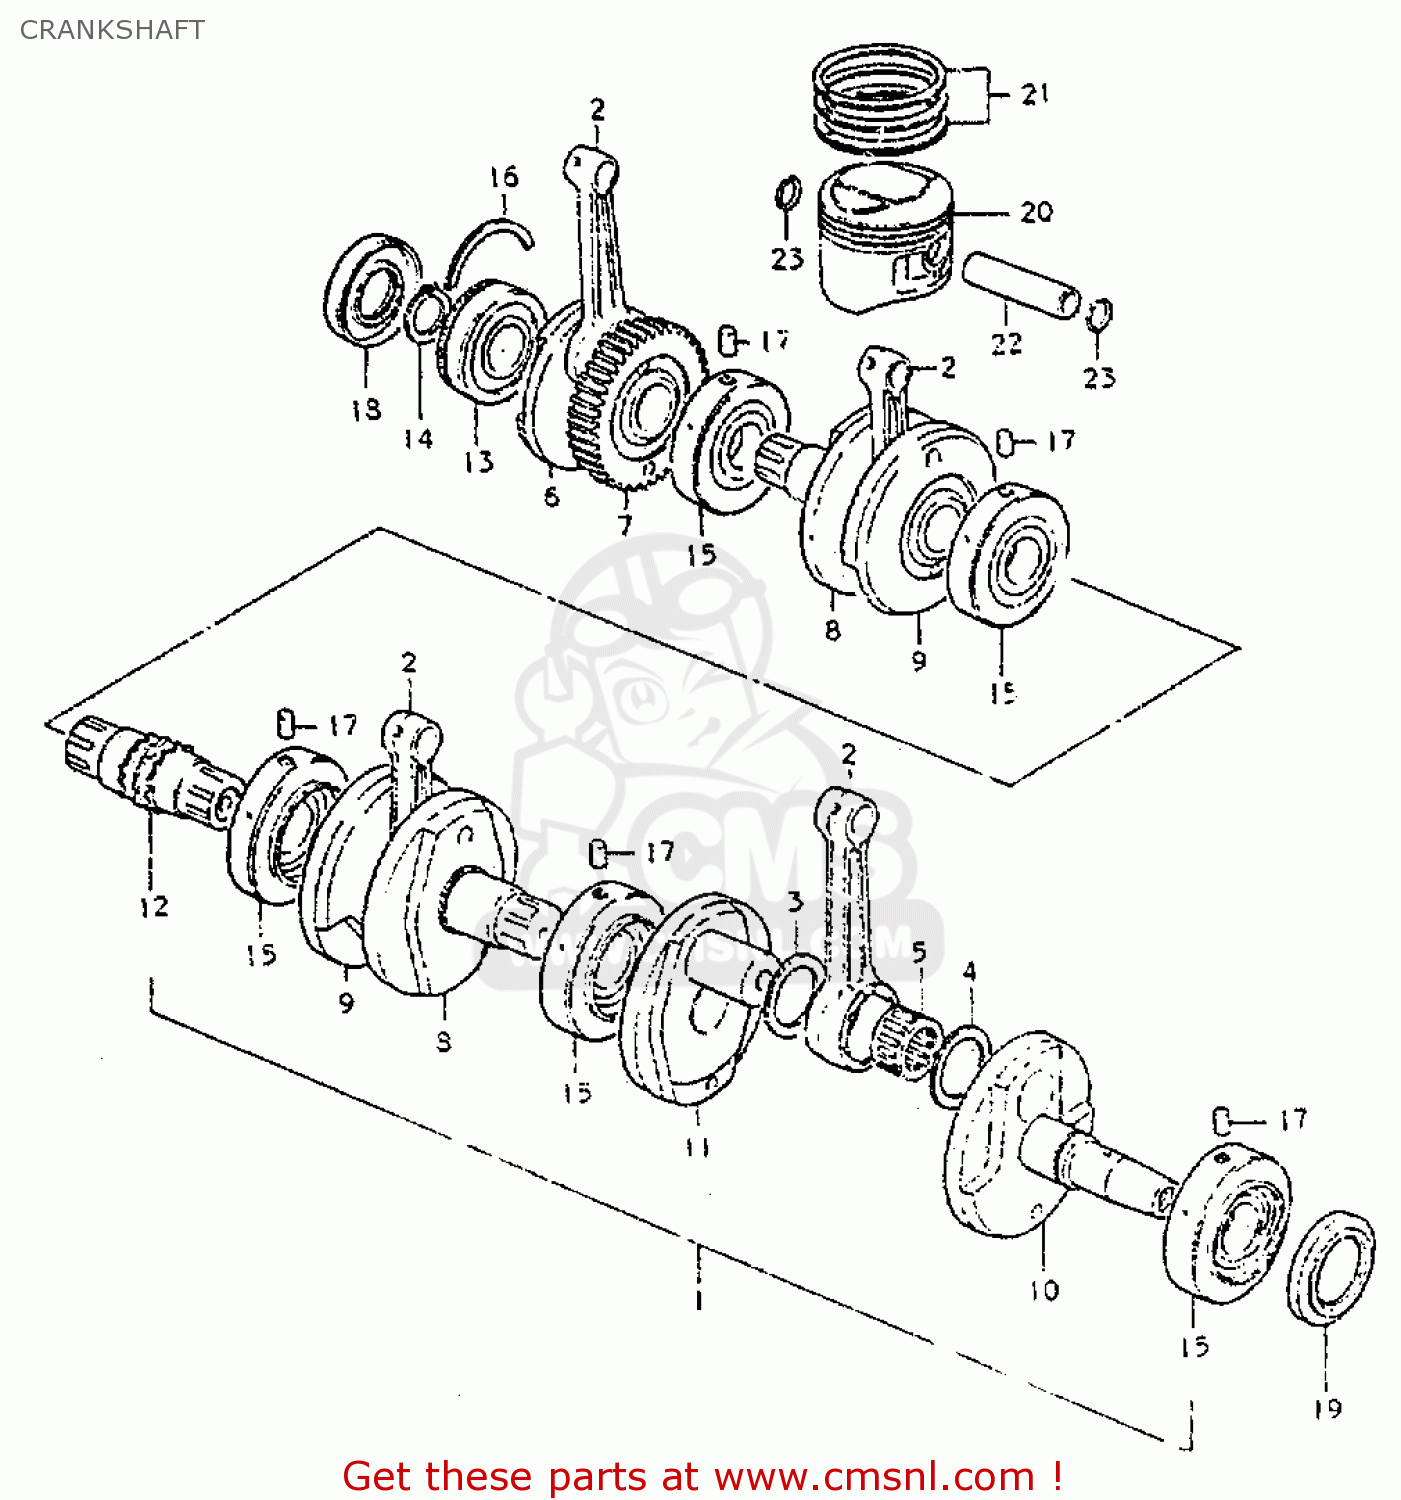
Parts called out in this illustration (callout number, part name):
1	CRANKSHAFT ASSEMBLY
2	ROD,CONNECTING
3	WASHER (28X48X2)
4	WASHER(28X48X1)
5	ROLLER BEARING (28X38X16.8)
6	CRANKSHAFT
7	WEB,CRANK
8	CRANKSHAFT
9	WEB,CRANK,MIDDLE
10	CRANKSHAFT,LEFT
11	WEB,CRANK,LEFT
12	SHAFT,TIMING CHAIN DRIVE
13	BEARING(30X72X19)
14	CIRCLIP,30MM
15	BEARING
16	C RING
17	PIN
18	SEAL,OIL(30X72X11)
19	OIL SEAL
20	PISTON
21	RING SET,PISTON
22	PIN,PISTON 16MM
23	CIRCLIP
